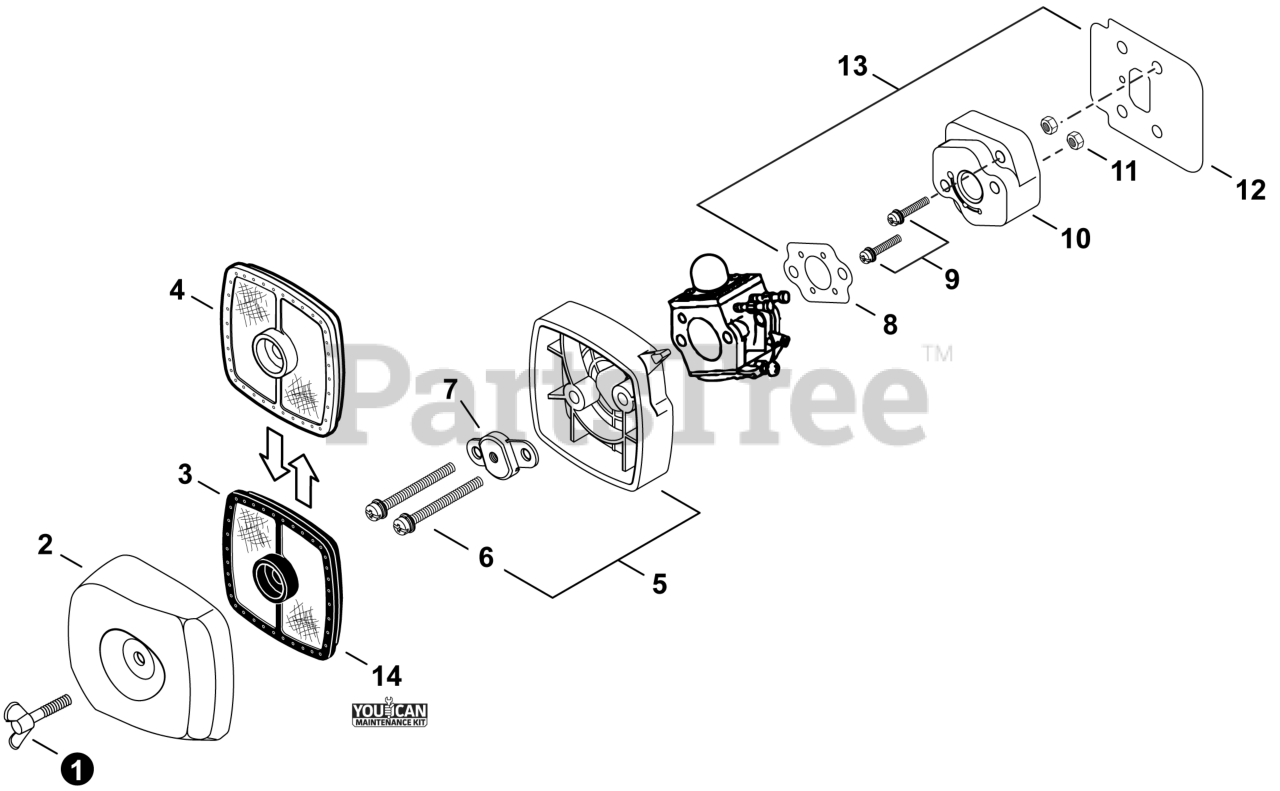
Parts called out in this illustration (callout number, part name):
1	BOLT, WING 5x20
2	COVER, AIR FILTER - BLACK
3	FILTER, AIR - DOUBLE LAYER
4	FILTER, AIR - SINGLE LAYER
5	CASE SET, AIR FILTER
6	SCREW 5x65
7	PLATE, PREVENT
8	GASKET, INTAKE
9	SCREW 5x20
10	INSULATOR, INTAKE
12	HEAT SHIELD, INTAKE
13	GASKET KIT: ENGINE, INTAKE, EXHAUST
14	TUNE-UP KIT - YOUCANT
